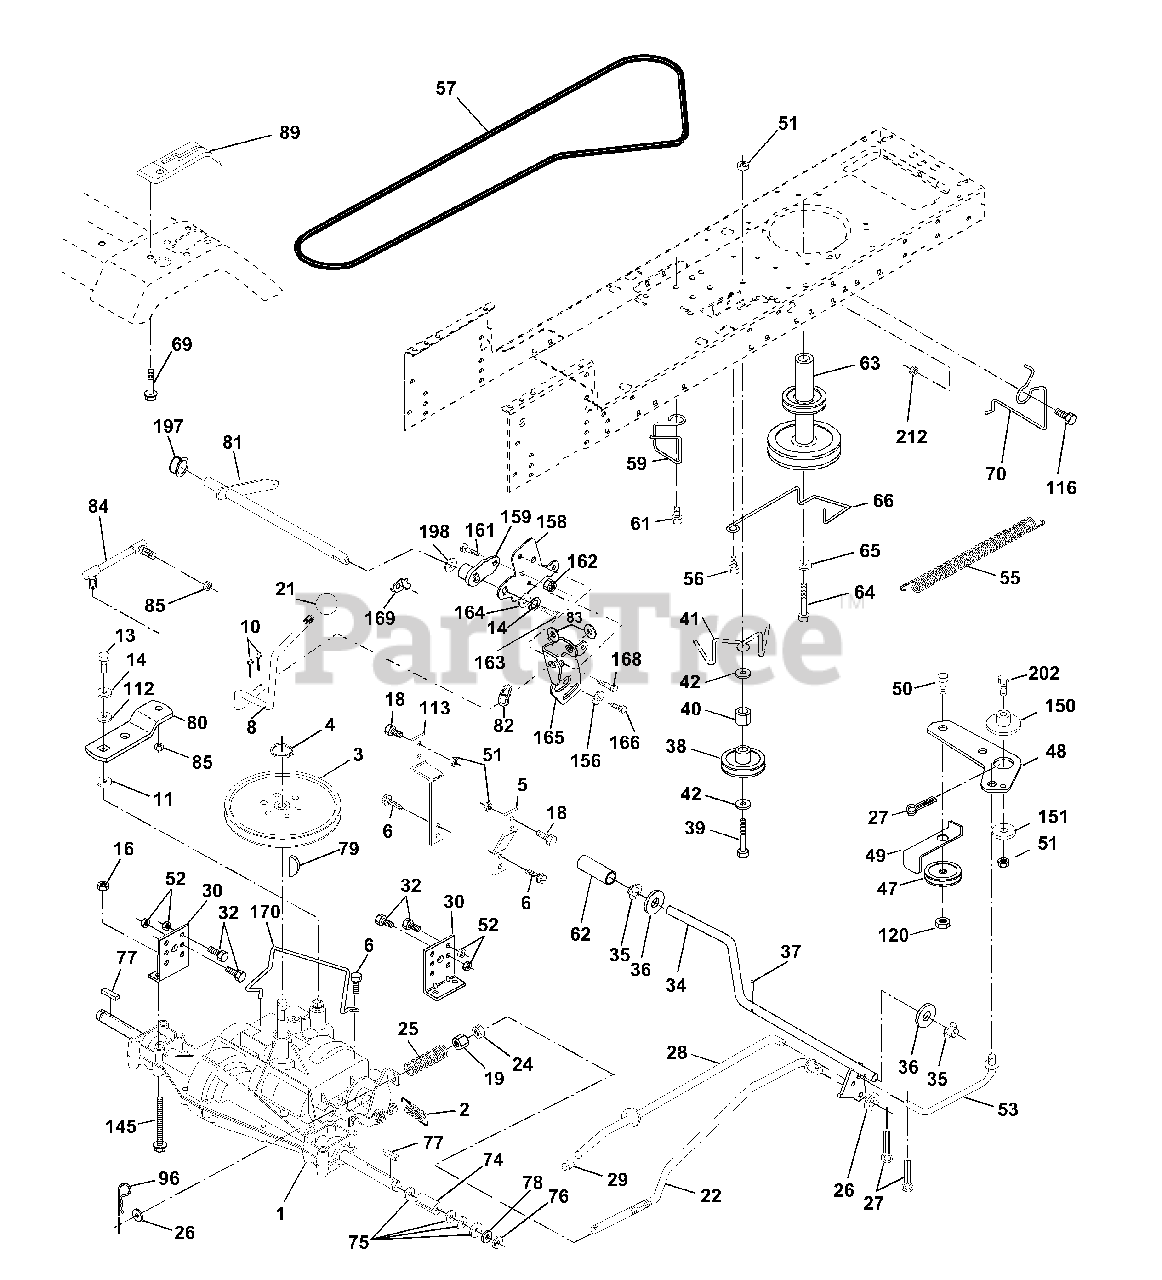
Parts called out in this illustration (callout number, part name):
2	Spring Return Brake T/a Zinc
3	Pulley Transaxle 18" tires
4	Ring Retainer # 5100-62
5	Strap Torque 30 Degrees
6	Screw 5/16-18 X 3/4
8	Rod Shift Fender Adjust Lt
10	Pin Cotter 1/8 X 1 Cad
11	Washer Plate Shf 388 Sq Hole
13	Bolt 1/4-28 Unf Gr 8 W/Patch
14	Washer Lock Hvy Helical
16	Nut Lock Hex w/ins 5/16-18
18	Bolt, Fin Hex 3/8-16 UNC x 1 Gr. 5
19	Nut Lock 3/8-16 Unc
21	Knob
22	Rod Brake Blk Zinc 26 840
24	Nut Hex Jam 3/8-16 Unc
25	Spring Rod Brake 2 00 Zinc
26	Washer 13/32 X 13/16 X 16 Ga
27	Pin Cotter 1/8 X 3/4 Cad
28	Rod Brake Parking LT/YT
29	Cap Brake Parking
30	Bracket Mtg Transaxle
32	Bolt Hex Hd 5/16-18unc X 3/4
34	Shaft Asm Pedal Foot
35	Bearing Nylon Blk 629 Id
36	Washer 21/32 X 1 X 16 Ga
37	Pin Roll 3/16 X 1"
38	Pulley Composite Flat
39	Bolt Fin Hex 3/8-16 unc X 3
40	Spacer Split Steel
41	Keeper Belt Flat Idler
42	Washer 13/32 X 13/16 X 12 Ga
47	Pulley Idler V Groove Plastic
48	Bellcrank Asm
49	Retainer Belt Style Spring
50	Bolt Hex Hd 3/8-16unc X 1-1/2
51	Nut Crownlock 3/8-16 Unc
52	Nut Crownlock 5/16-18 Unc
53	Link Clutch
55	Spring Return Clutch 6 75
56	Screw 3/8-16 x 1
57	V-Belt Ground Drive 95 25
59	Keeper Belt Span Ctr
61	Screw 3/8-16x.75
62	Cover Pedal Blk Round
63	Engine Pulley
64	Bolt Hex
65	Washer Lock Hvy Hlcl Spr 7/16
66	Keeper Belt Engine Foolproof
69	Screw Hex wsh Hi Lo 1/4 x 1/2 unc
70	Guide Belt Mower Drive RH
74	Spacer Axle
75	Washer 25/32 X 1 1/4 X 16 Ga
76	E-ring #5133-75
77	Key Square 2 0 X 1845/ 1865
78	Washer 25/32 X 1-5/8 X 16 Ga
79	Key Woodruff #9 3/16 x 3/4
80	Arm Shift
81	Shaft Asm Cross Tapered PMST/20
82	Spring Torsion T/a
83	Washer 17/32 X 3/4 X 16 Ga
84	Link Transaxle PMST/20" Zinc
85	Nut Lock Center 1/4 - 28 FNTHD
89	Console Shift STLT
96	Retainer Spring 1"
112	Washer 9/32 x 3/4 x 10 Ga.
113	Strap Torque LT
116	Bolt Rdhd Sq Neck 3/8-16 x 1
120	Nut Lock Flg. 3/8-16 Unc
145	Bolt Hex FLGHD 5/16-18 Gr. 5
150	Spacer Retainer
151	Washer 13/32 x 2 x 10
156	Washer Srrted 5/16ID x 1.125
158	Bracket Shift Mount
159	Hub Tapered Flange Shift Lt
161	Bolt Rdhd Sqnk 1/4-20 x 3/4 Gr
162	Nut Crownlock 1/4-20 Unc
163	Bolt Hex Fin 1/4-20 Unc x 1 Gr 5
164	Washer 5/8 x .281 x 10 Ga
165	Bracket Pivot Lever
166	Screw 5/16-18 x 5/8
168	Bolt Shoulder 5/16-18 x .561
169	Plate Fastening
170	Keeper Belt Transaxle Gear
197	Nyliner Snap-In
198	Washer Nyliner
202	Bolt Carr Sh 3/8-16 x 1-1/2 Gr. 5
212	Nut Hexflange Lock
